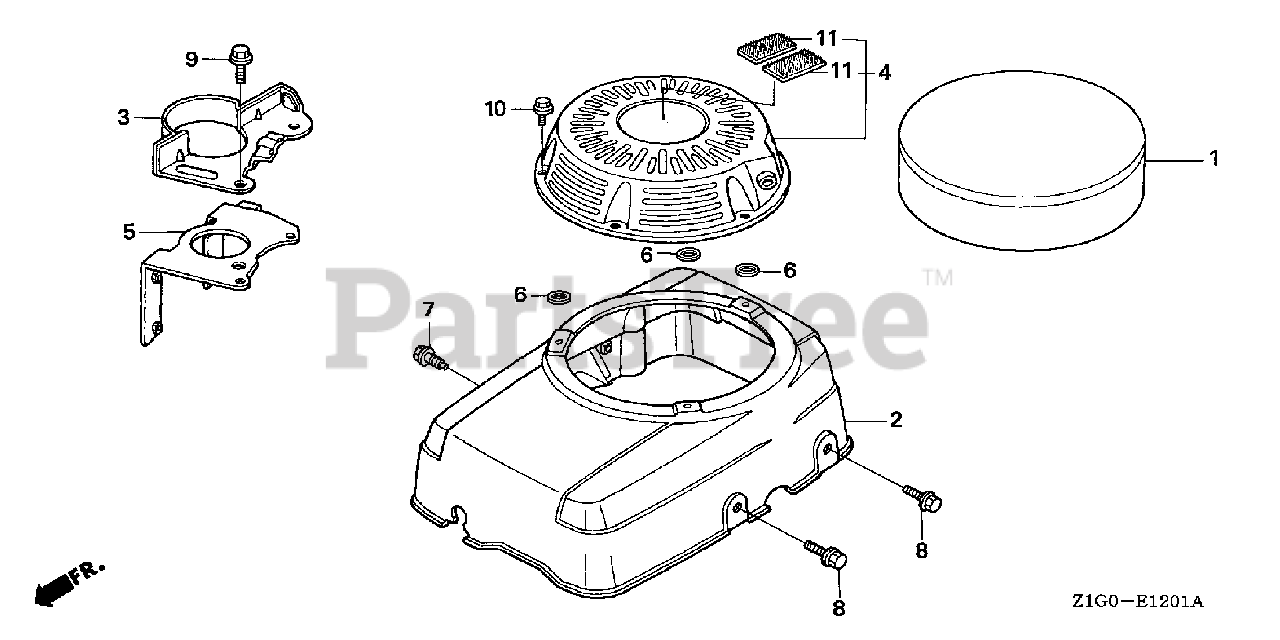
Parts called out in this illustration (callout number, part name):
1	FILTER, AIR
2	COVER, FAN *R280* (POWER RED)
3	PLATE, SIDE
4	HOOD, FAN COVER
5	STAY, STARTER
6	COLLAR, TAILLIGHT
7	BOLT, FLANGE (6X12) (CT200)
8	BOLT, FLANGE (8X16)
9	BOLT, FLANGE (8X28)
10	BOLT, FLANGE (6X12)
11	TAPE, MAGIC (25X50) (FEMALE)
